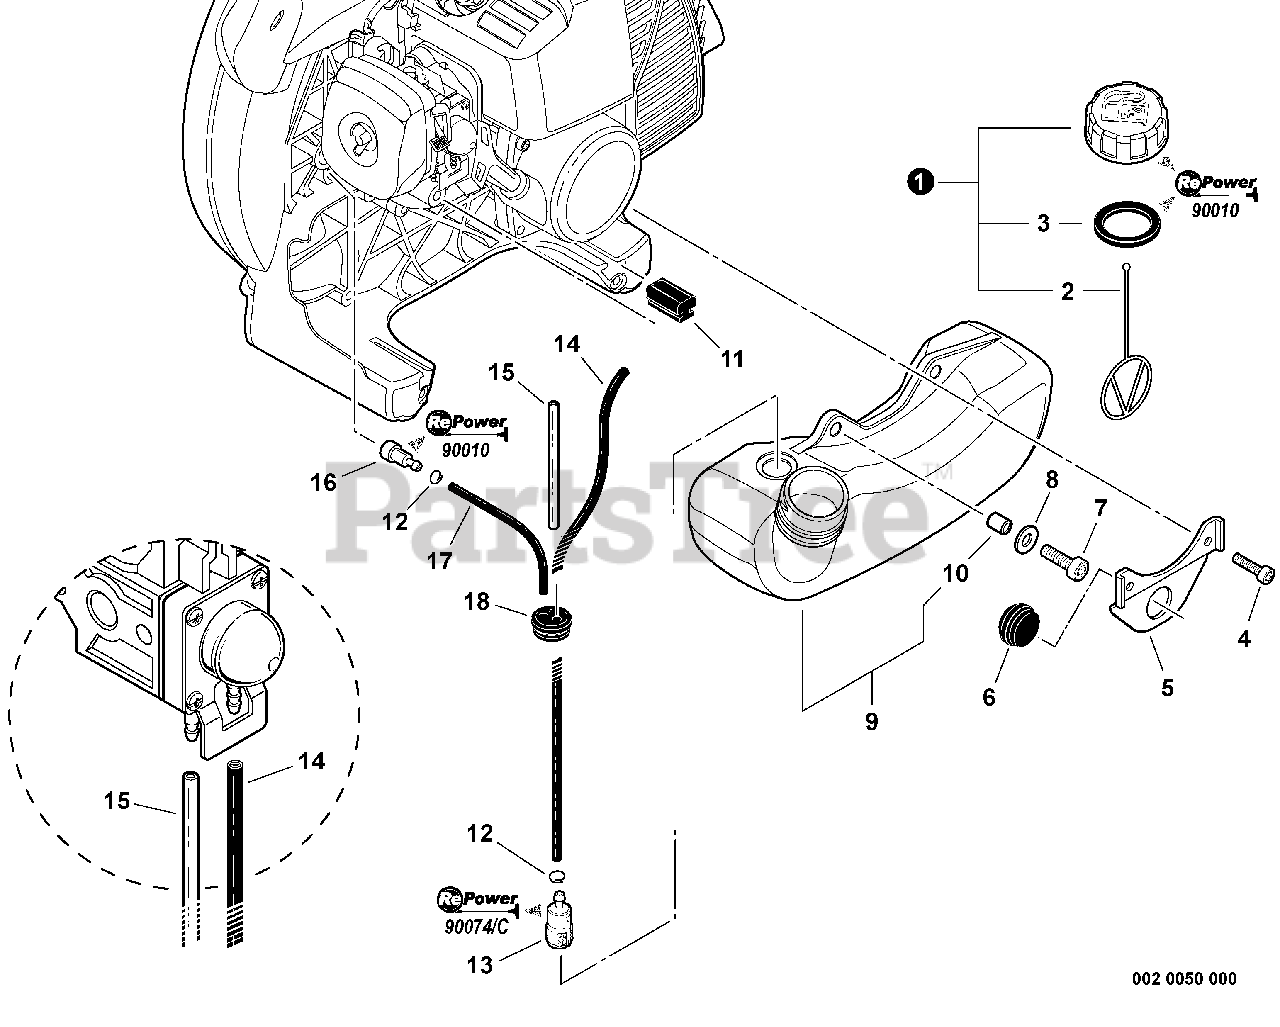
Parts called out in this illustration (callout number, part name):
1	CAP ASSY - ORANGE
2	CONNECTOR, CAP
3	GASKET, CAP
4	SCREW - 4X16
5	BRACKET, FUEL TANK
6	CUSHION
7	SCREW - 5X16
8	WASHER - 5
9	FUEL TANK ASSY
12	CLIP - 6
13	FILTER, FUEL
14	PIPE - 3X5X210 -- BLACK
15	PIPE - 3X6X85 -- CLEAR
16	VENT, FUEL TANK
17	PIPE - 3X6X80 -- BLACK
18	GROMMET
19	Repower CAP AND VENT KIT
20	RePower TUNE-UP KIT
